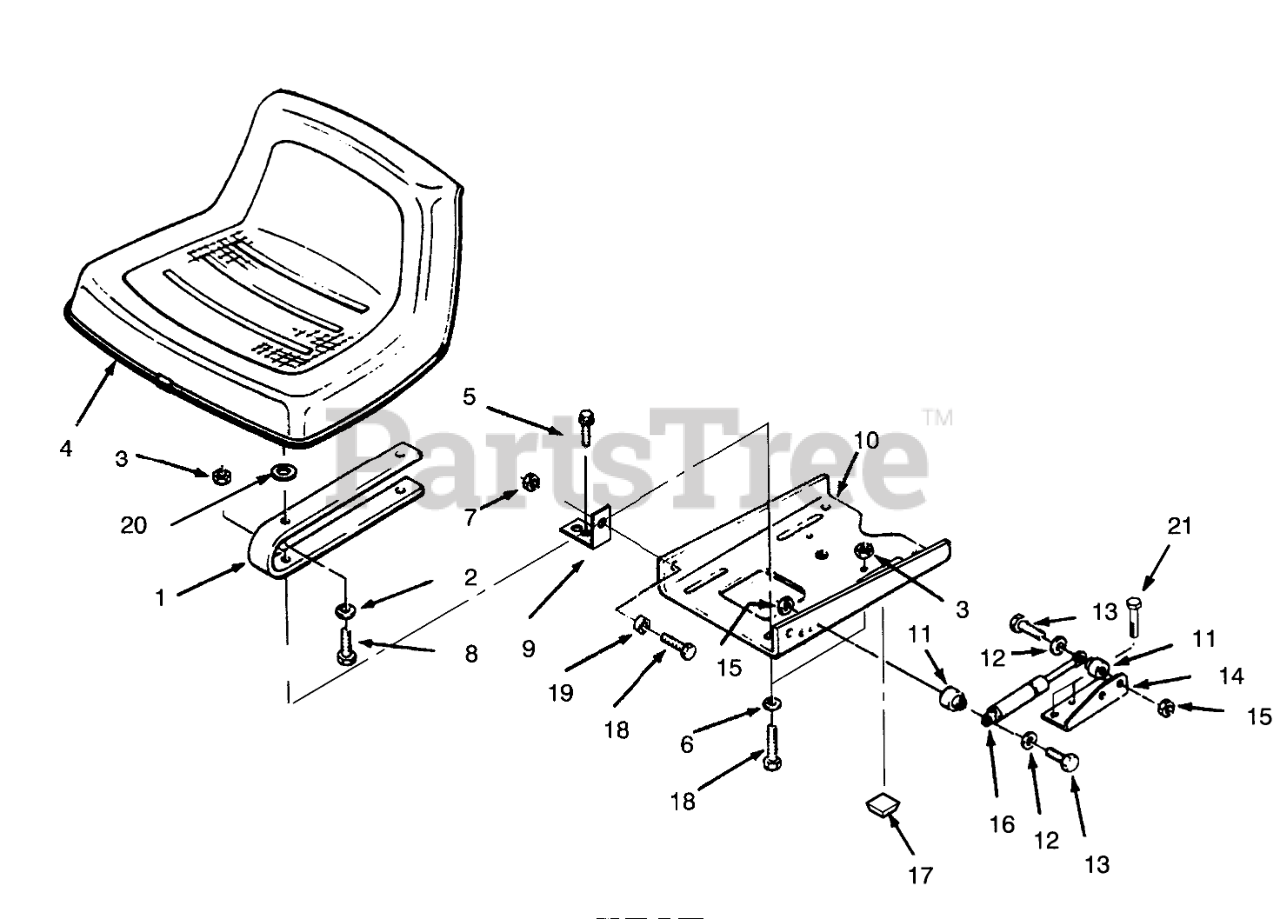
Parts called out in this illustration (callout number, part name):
1	Seat Spring
2	WASHER-LOCK
3	NUT-LOCK, NI
4	SEAT V-510
5	Bolt
6	WASHER-PLAIN
7	NUT-LOCK, NI
8	SCREW-HH
9	BRACKET-PIVOT
10	Plate-SeatPivot
11	SPACER
12	WASHER-FLAT
13	SCREW-HH
14	BRACKET-CYLINDER R
15	NUT-LOCK, NI
16	GAS SPRING
17	BUMPER SJ5514 BLACK
18	SCREW-HH
19	BUSHING
20	SPACER-NYLON
21	Bolt
